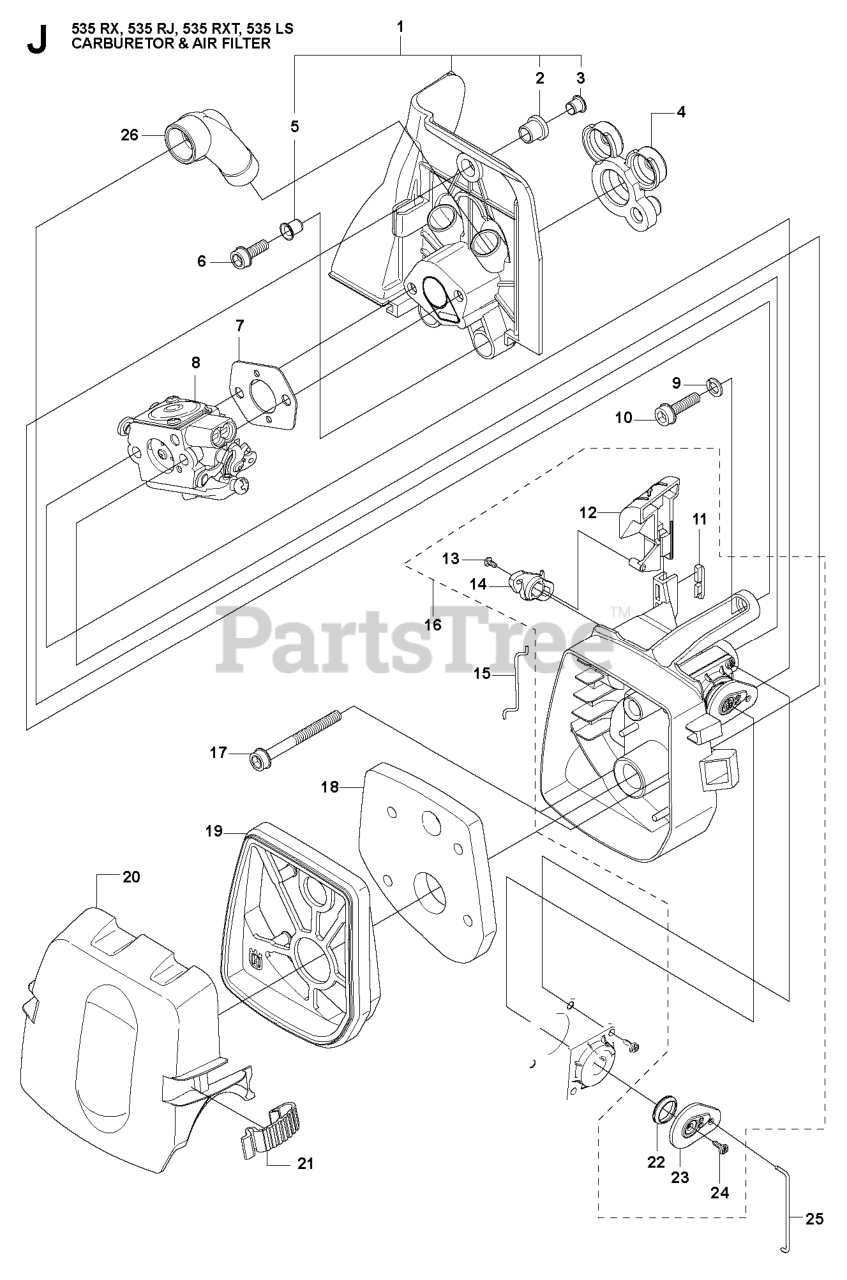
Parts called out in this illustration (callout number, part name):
8	CARBURETTOR
12	CHOKE CONTROL
15	THROTTLE ROD
16	FILTER HOLDER
18	AIR FILTER
20	COVER, AIR FILTER
25	THROTTLE ROD
